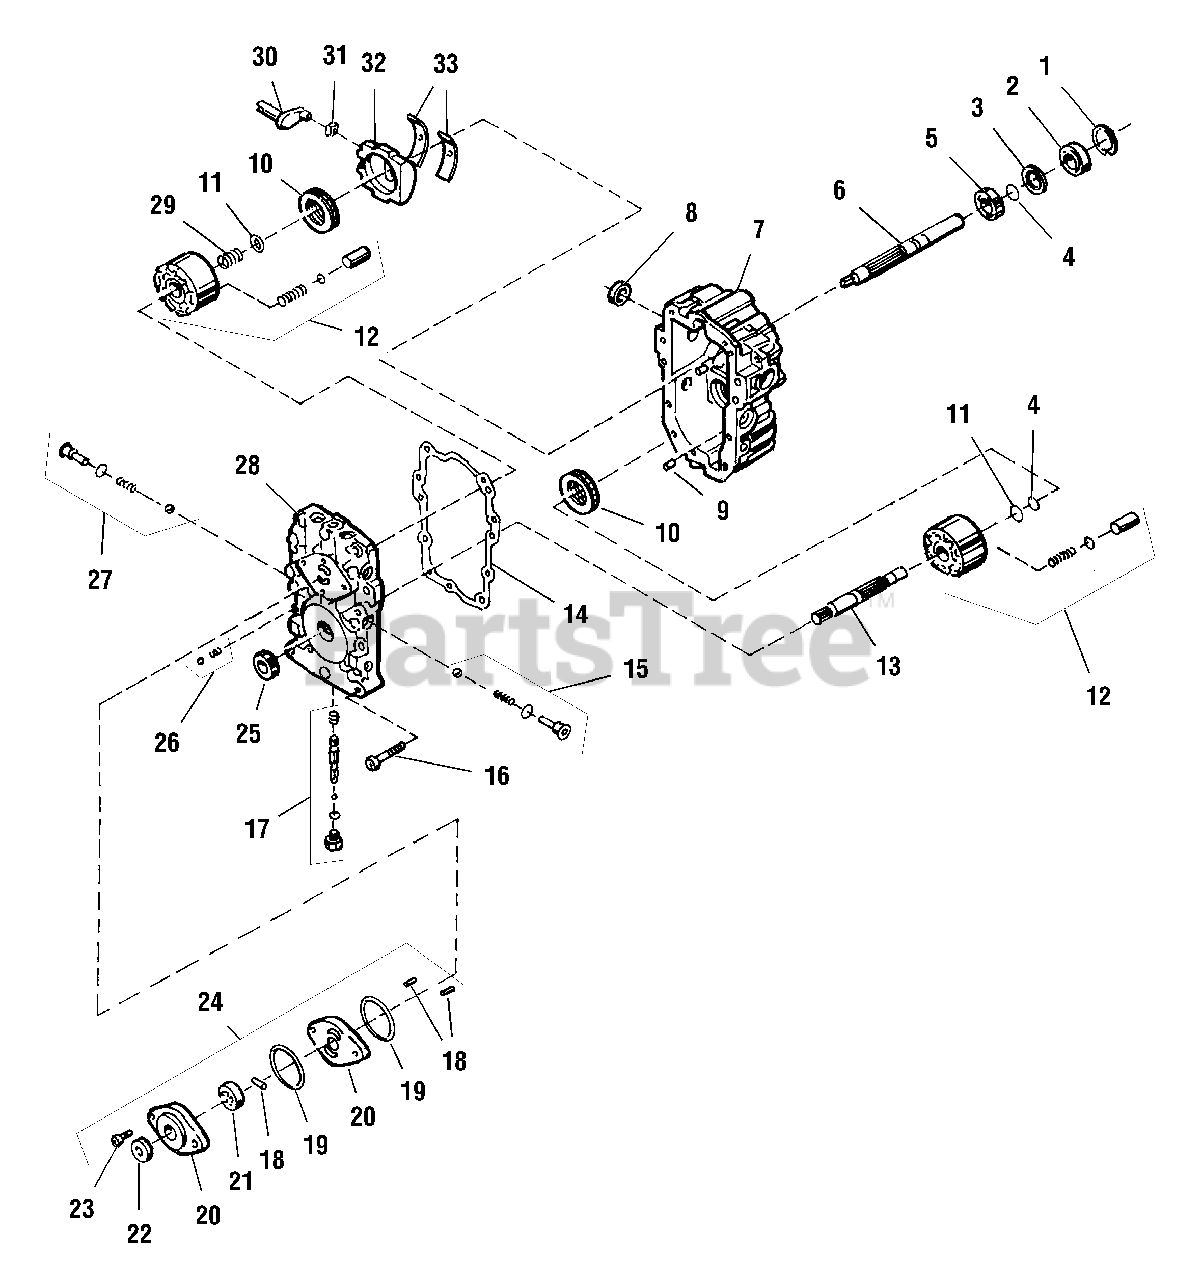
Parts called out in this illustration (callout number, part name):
1	RETAINING RING
2	SEAL
3	SPACER
4	Retaining Ring
5	BEARING. Shaft
7	PUMP HOUSING KIT
8	SEAL
10	THRUST BEARING ASSY.
11	THRUST WASHER
12	BLOCK ASSY.
13	MOTOR SHAFT
14	GASKET, Center Section
15	CHECK VALVE KIT, LH
16	CAPSCREW, Socket Hd.
17	BYPASS VALVE KIT
19	O-RING
20	SPACER PLATE
21	GEROTOR ASSY.
22	SEAL
23	CAPSCREW, 6M x 20
24	CHARGE PUMP KIT
25	SEAL
26	CHARGE RELIEF KIT
27	CHECK VALVE KIT, RH
28	CENTER SECTION KIT
30	TRUNNION ARM
32	VARIABLE SWASHPLATE
33	CRADLE, Bearing
